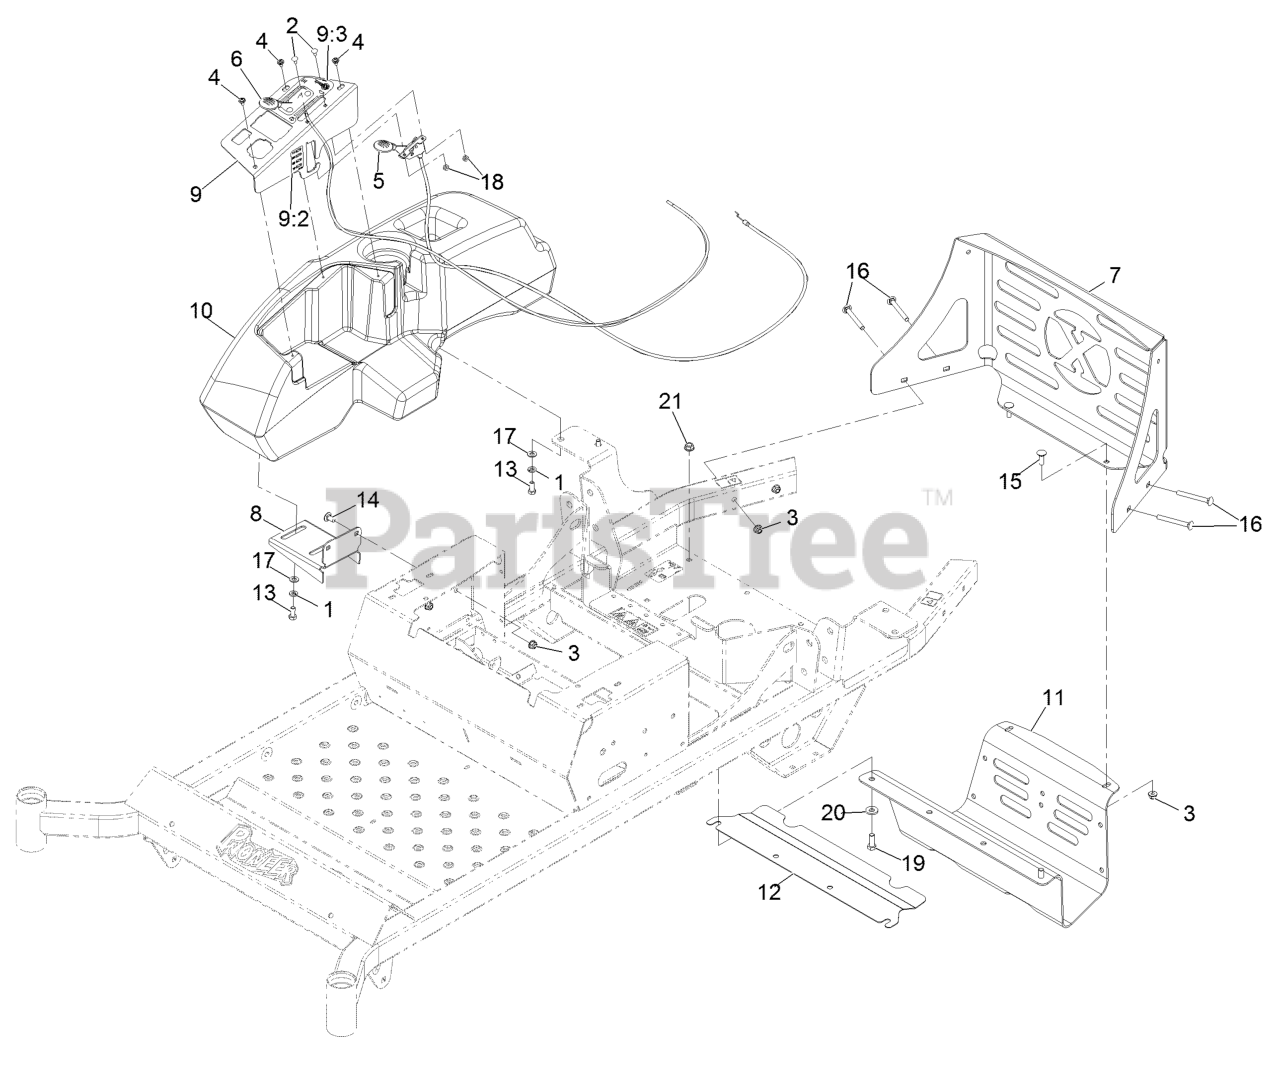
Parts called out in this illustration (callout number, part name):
1	WASHER-LOCK
2	BOLT-CARR
3	NUT-HF, NI
4	SCREW-PPH
5	CONTROL-THROTTLE
6	CONTROL-CHOKE
7	PANEL,REAR GUARD
8	BRACKET-TANK AND FENDER
9	ASM, CONTROL PANEL W/ DEC
9:2	DECAL,FUSE BLOCK
9:3	DECAL-THROTTLE CHOKE
10	CONSOLE,RH
11	GUARD, MUFFLER
12	SHIELD, HEAT
13	SCREW-HH
14	SCREW-CARR
15	BOLT-CARR
16	SCREW-CARR
17	WASHER-PLAIN
18	NUT-LOCK, NI
19	SCREW-HH
20	WASHER-BELLEVILLE
21	NUT-HHF, WHIZ
